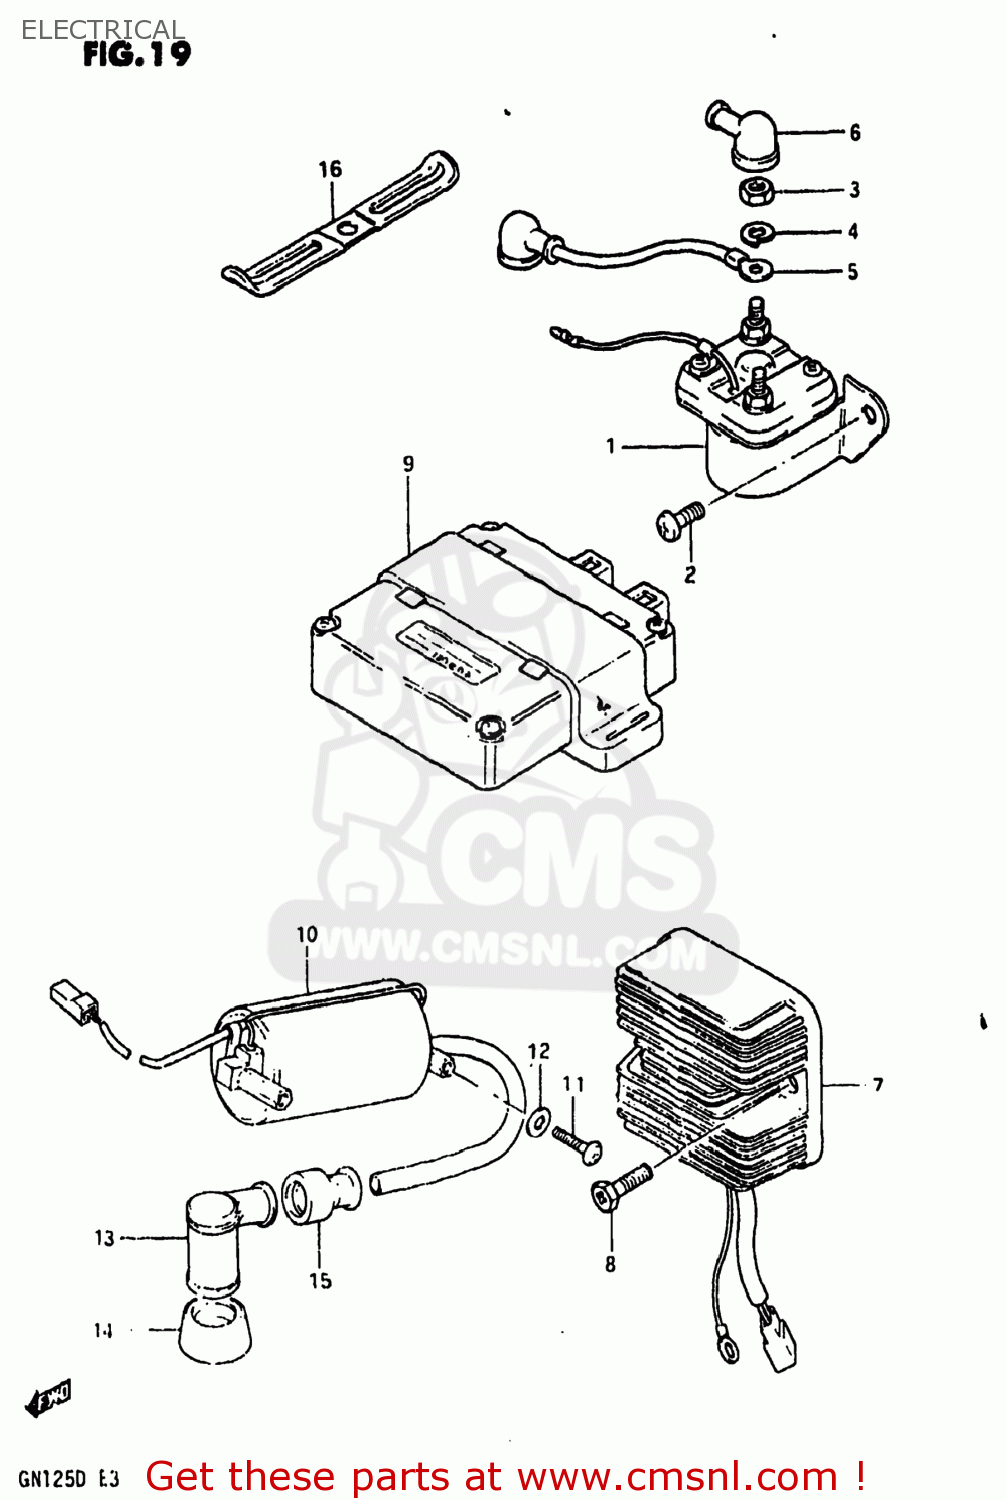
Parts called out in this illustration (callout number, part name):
1	RELAY ASSY,STARTING MOTOR
2	SCREW
3	NUT 6MM
4	LOCK WASHER
5	WIRE,STARTER MOTOR LEAD
6	CAP,STARTER MOTOR TERMINAL
7	RECTIFIER ASSEMBLY
8	SCREW(6X12)
9	IGNITOR UNIT
10	COIL ASSEMBLY,IGNITION
11	SCREW
12	WASHER
13	CAP ASSY,SPARK PLUG
14	SEAL,SPARK PLUG
15	SEAL,SPARK PLU
16	CLAMP,WIRING HARNESS
